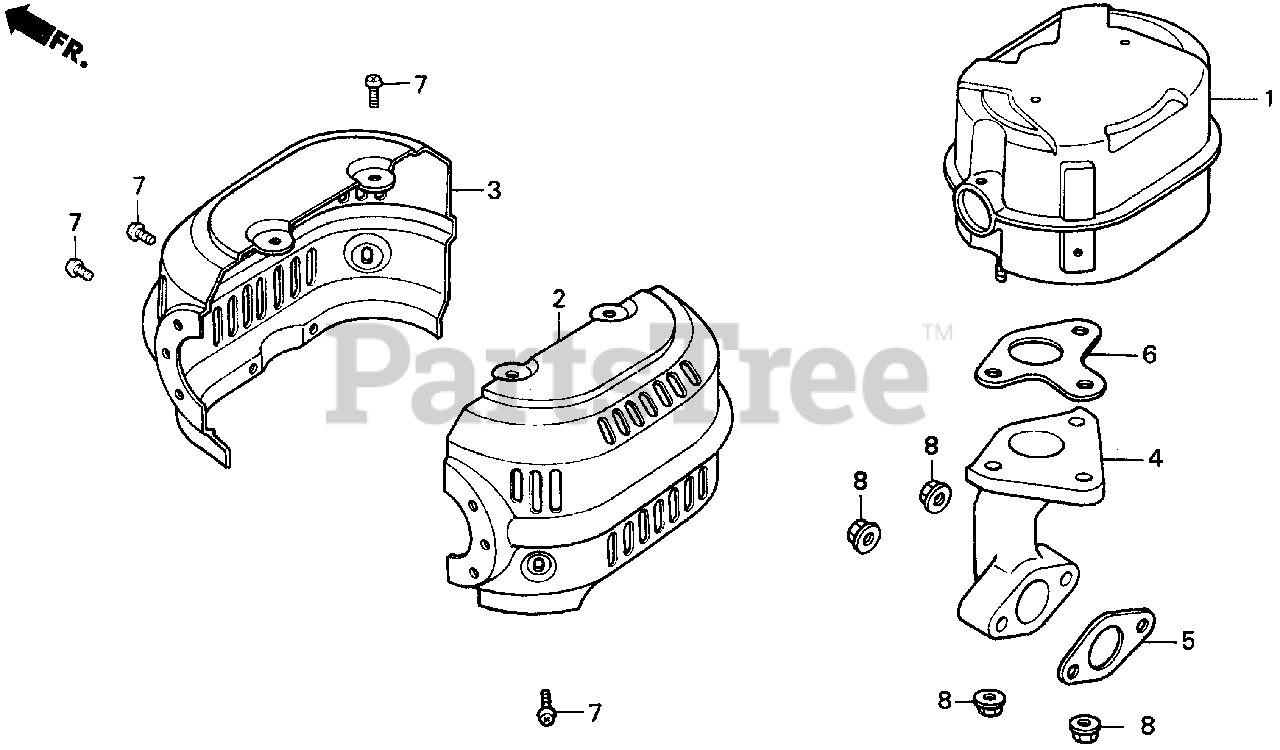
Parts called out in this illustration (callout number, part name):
2	PROTECTOR, R. MUFFLER (ALUMINIZED)
3	PROTECTOR, L. MUFFLER (ALUMINIZED)
5	GASKET, EX. PIPE
5	GASKET, EX. PIPE (WACKER)
6	GASKET, MUFFLER
7	SCREW, TAPPING (5X8)
8	NUT, FLANGE (8MM)
